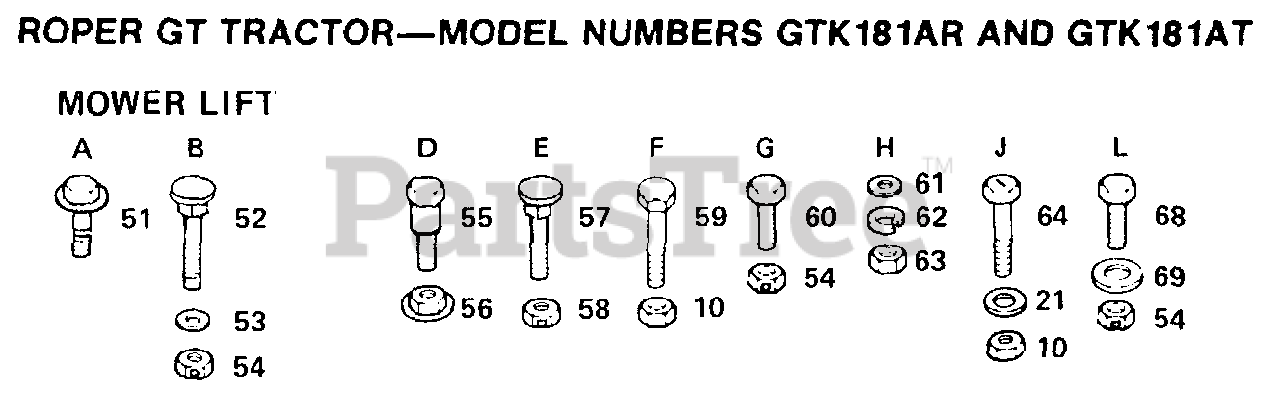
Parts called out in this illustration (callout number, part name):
21	WASHER
51	SCREW LT
52	BOLT
53	WASHER
55	SHOULDER BOLT T
56	NUT T
57	BOLT
58	LOCKNUT
59	BOLT
61	WASHER PM
68	BOLT
69	WASHER M
